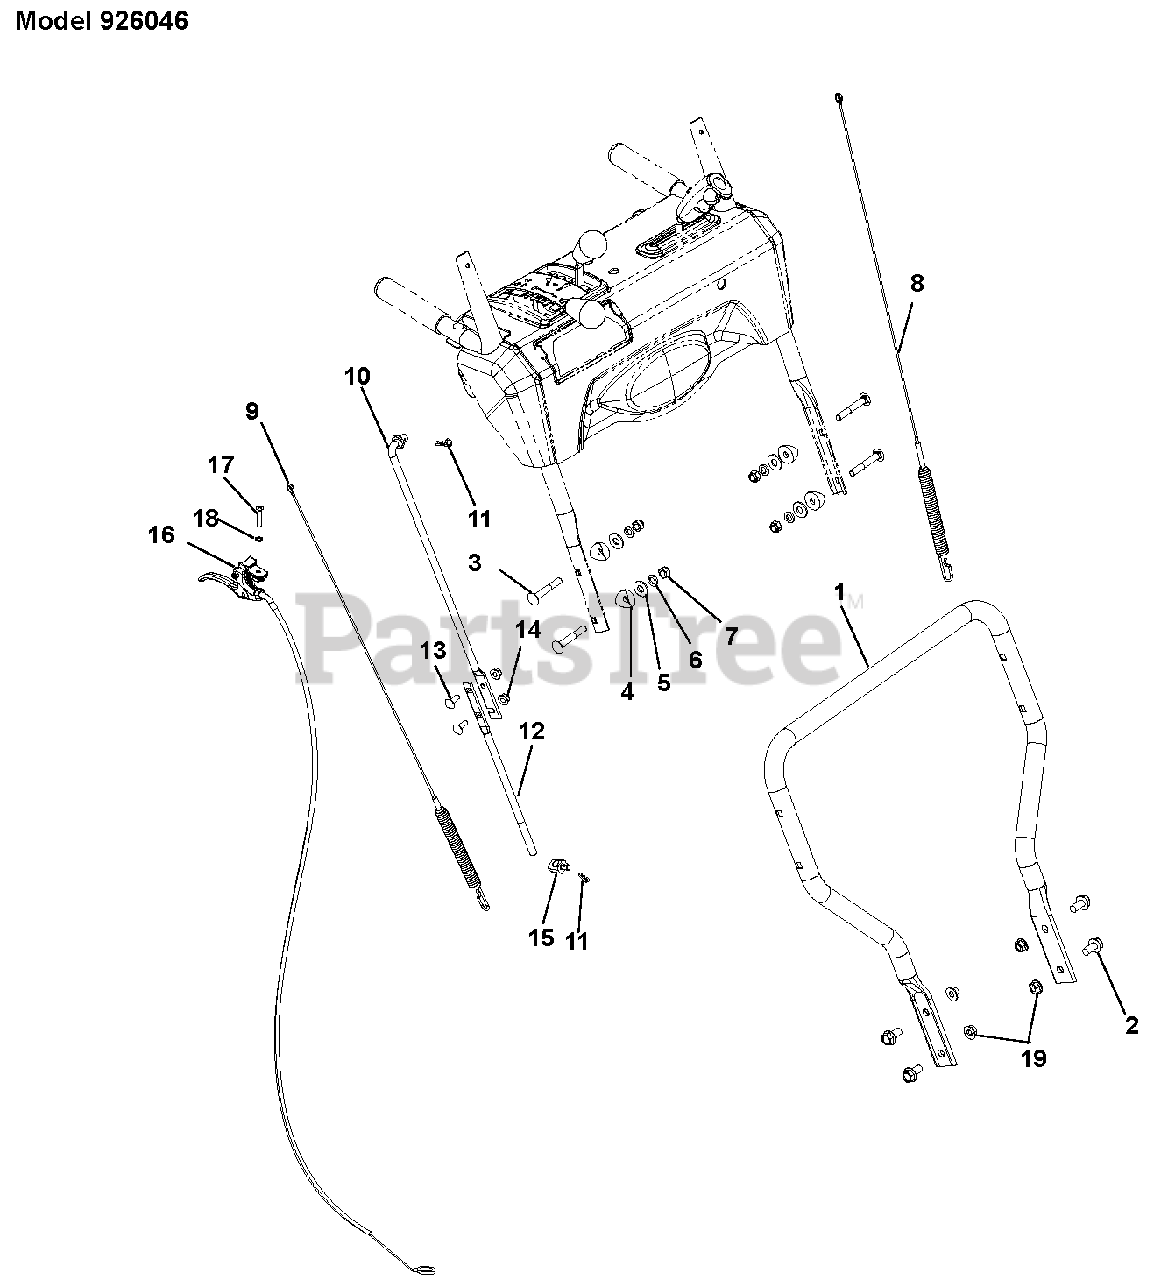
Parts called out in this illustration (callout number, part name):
1	Handlebar, Lower
2	Bolt, Serrated Hex Flange Washer Head .38-16 x .75
3	Bolt, Round Head Square Neck .31-18 x 2.25
4	Spacer, Handlebar
5	Washer, Flat Steel .38 x .875 x .083
6	Washer, Lock .312 x .097
7	Nut, Locking Nylon .31-18
8	Cable, Traction
9	Cable, Auger
10	Rod, Shift, Upper
11	Pin, Hair, Internal .08 x .18 x 1.18
12	Rod, Shift, Lower
13	Bolt, Round Head Square Neck .25-20 x .75
14	Nut, Locking Top Flange .25-20
15	Pivot, Shift Rod
16	Cable, Remote Brush Lock
17	Screw, Machine, Oval Head .25-20 x 1.50
18	Washer, Lock, Internal .25
19	Nut, Locking Top Flange .38-16
